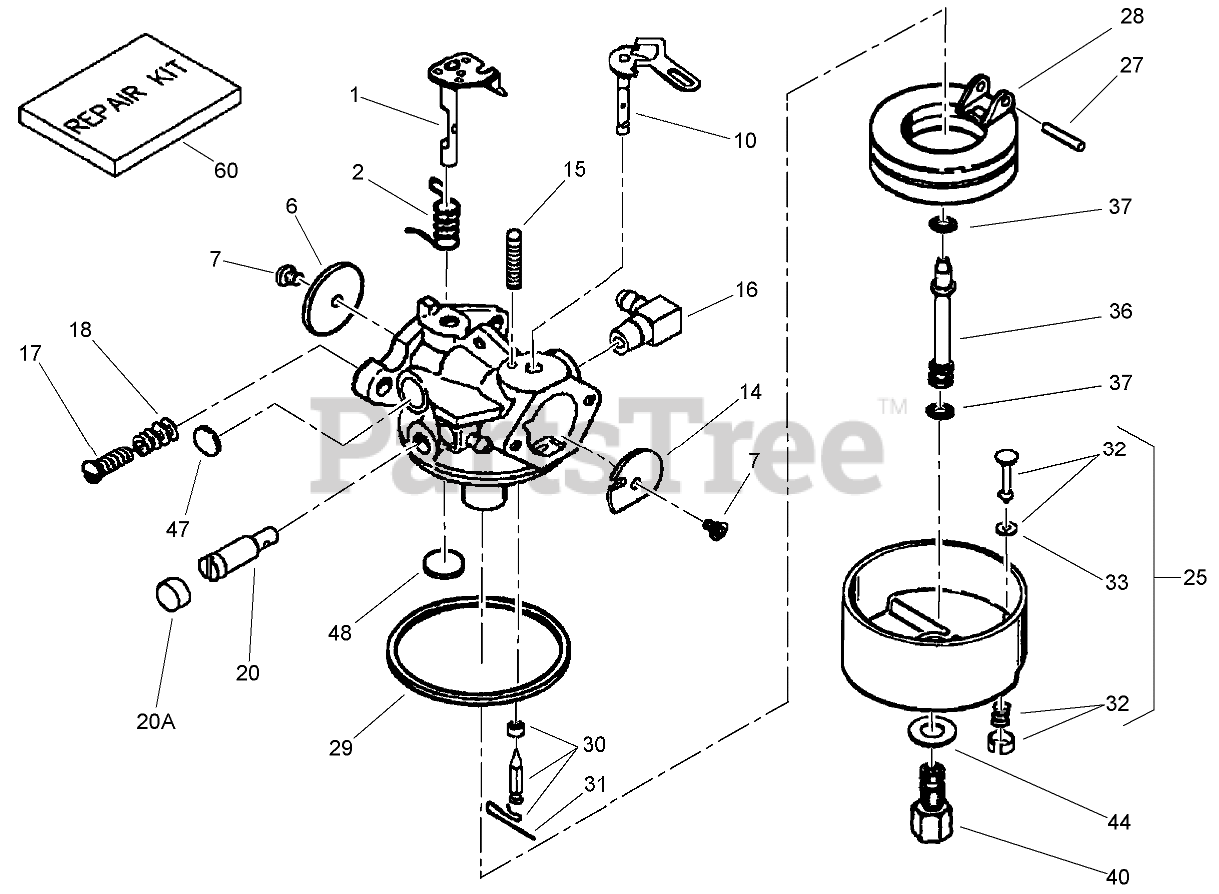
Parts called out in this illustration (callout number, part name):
1	Throttle Shaft and Lever ASM
2	Spring-Return, Throttle
6	Shutter-Throttle
7	Screw-Shutter
10	Choke Shaft and Lever Asm
14	Shutter-Choke
15	Spring-Positioning, Choke
16	Fitting-Fuel
17	Screw-Throttle Crack and Idle Speed
18	Spring-Tension
20	Screw-Restrictor, Idle
20A	Cap-Screw, Idle Restrictor
25	Bowl-Float (no drain)
25	Float Bowl ASM
27	Shaft-Float
28	Float (Plastic)
29	O Ring-Bowl, Float
30	Inlet Needle, Seat and Clip ASM
31	Clip-Spring
32	Bowl Drain ASM
33	Gasket-Plunger, Drain
36	Tube-Nozzle, Main
37	O-Ring
40	Nut-Bowl, High Speed
44	Washer-Nut, Bowl
47	Plug-Welch, Idle Mixture Well
48	Plug-Welch, Atmospheric Vent
60	Carburetor Repair Kit
